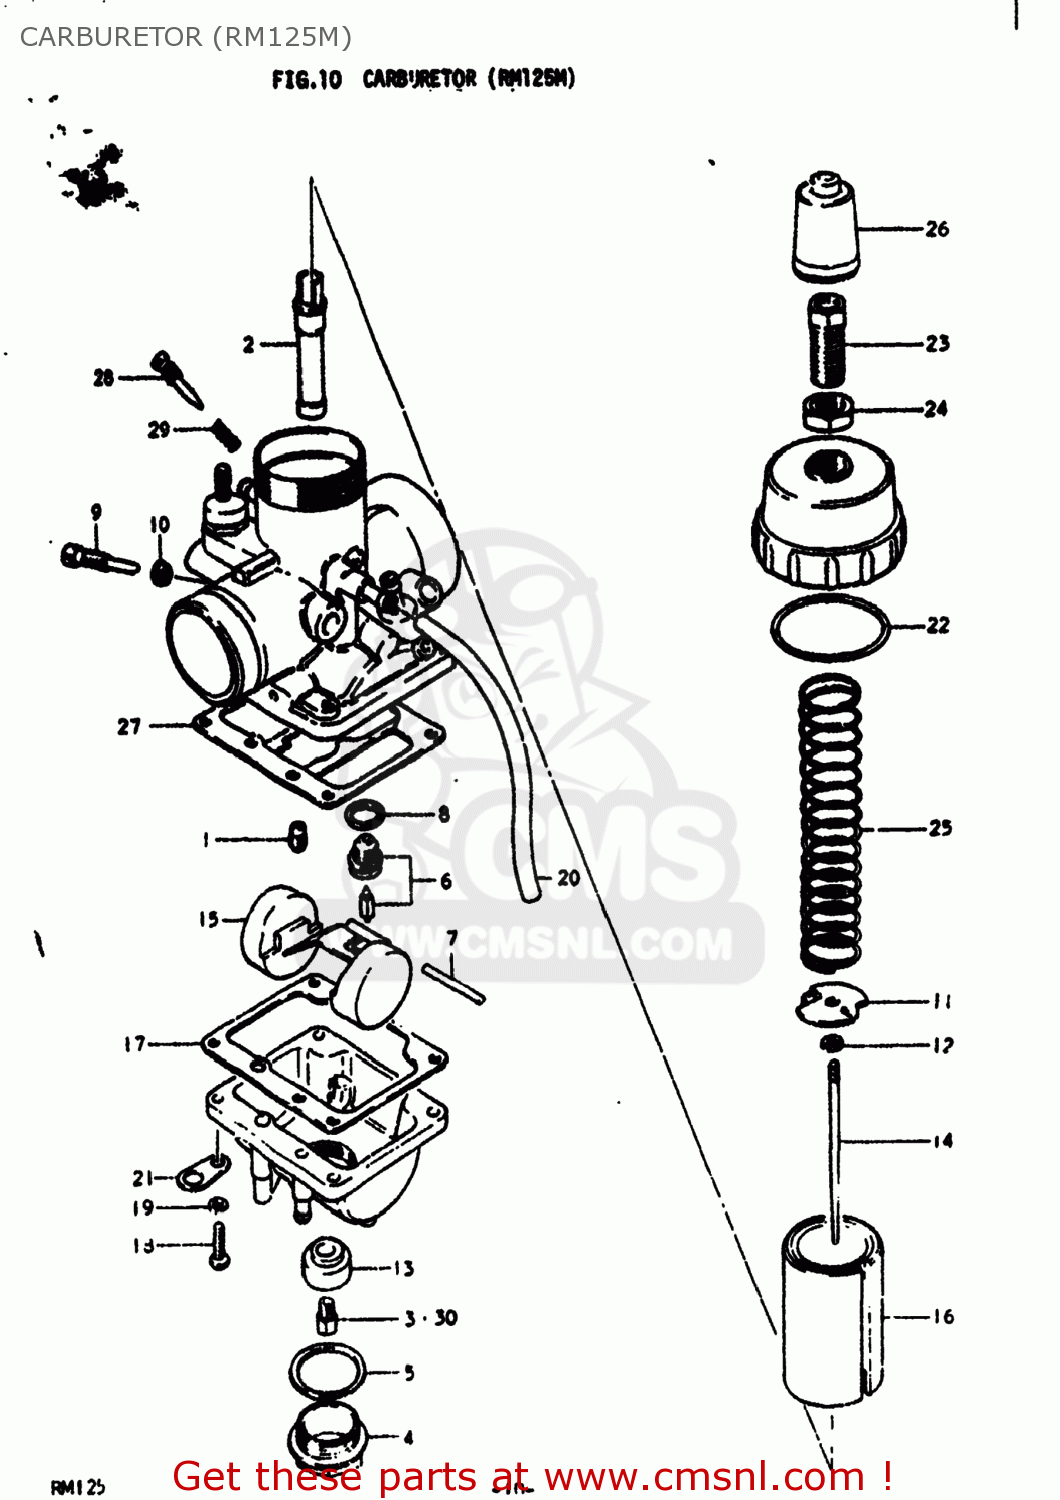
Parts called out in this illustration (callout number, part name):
1	JET,PILOT(50)
2	JET,NEEDLE
3	JET
4	PLUG
5	GASKET,DRAIN PLUG (MCA)
6	VALVE ASSEMBLY,NEEDLE
7	PIN,FLOAT
8	GASKET
9	ADJUSTER
10	NUT, STOP SCREW
11	SEAT,THROTTLE VALVE SPRING
12	CLIP
13	RING
14	NEEDLE JET
15	FLOAT
16	VALVE,THROTTLE,RIGHT
17	GASKET,FLOAT CHAMBER
18	SCREW
19	LOCK WASHER
20	HOSE
21	PLATE
22	O-RING
23	ADJUSTER,CABLE
24	NUT,CABLE ADJUSTER LOCK
25	SPRING
26	CAP
27	PLATE
28	SCREW,PILOT AIR
29	SPRING
30	JET
